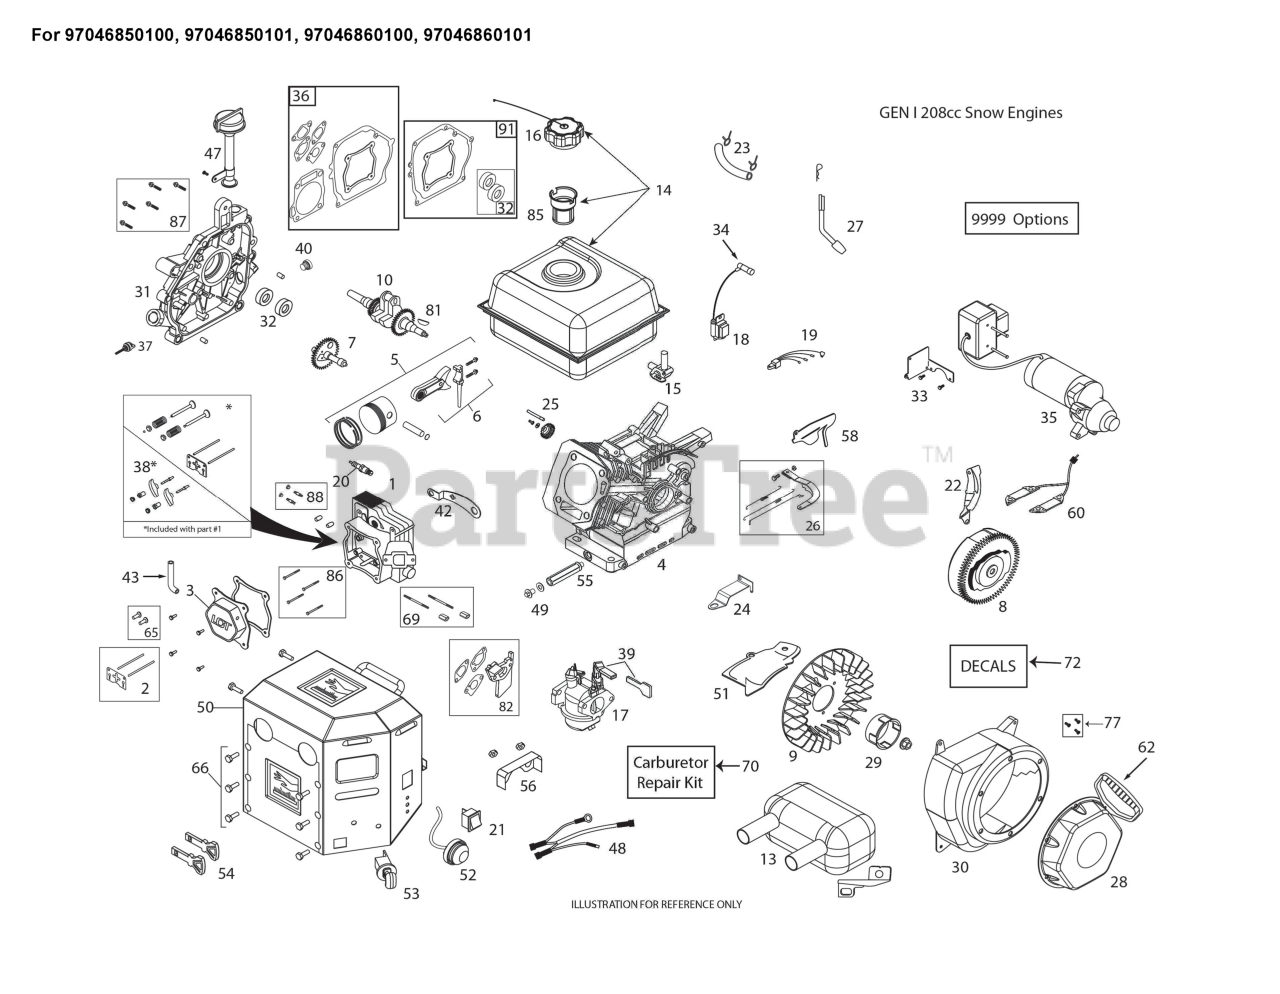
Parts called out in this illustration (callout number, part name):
1	CYLINDR.HEAD.SRV.KIT W/GASKET
2	KIT.PUSH.ROD.SRV(SK208-1001)
3	VALVE COVER LCT 179/208
5	KIT.PISTON.SRV(SK208-1400)
7	KIT.CAMSHAFT.208CC.LCT
8	FLYWHEEL ELECTRIC START W/6 MA
9	FLYWHEEL FAN 420586
10	CRNKSHFT-KYD#14.208CCSKSNO8001
13	MUFFLERS
13	Husqvarna TBD
13	MUFFLER KIT LCT SKSN2205.1
14	FUEL.TK.ASSY.GENII.SKSN0311.1
15	FUEL.PETCOCK.SNOW(SKSN4900)
16	FUEL CAP OVERSIZED CLICK STYLE
17	CARBURETORS
17	CARBURETTOR L10-1D.W/SP
18	208CC IGN COIL (STD)
20	SPARK.PLUG(2083810)
22	SHIELD.FLYWHEEL.ELEC.STRT.208C
23	KIT.FUEL.HOSE.208CC.SING/STAGE
24	SPEED.CTRL.BRKT.(SKSN0150)
25	GOVENOR.GEARS ASM(SK2082900)
26	CARBURETTOR GOVERNOR LINK.ASM.
27	KIT.GOVERNOR.CRANK(SK208-3100)
28	RECOIL.STRT.ROUND(BLK) SNOW
29	STRTER.CUP(NON-SLOT)SKSN0601.2
30	HOUSINGS
31	COVER CRANKCASE.LCT.SK2083605
32	SEAL KIT (2 PCS)
34	SPARK.PLUG.BOOT.SNW,SKSN4691.1
35	STARTER 230C EL START.LCT SKSN
35	ELEC.START.GEN2.SKSN0451.1
36	GASKET.KIT.208CC(SK2084300.1)
37	DIPSTICK SMALL
38	ROCKER ARM KIT
39	CHOKE.KNOW.SNOW(SKSN4500)
40	NON REMOVABLE PLUG
43	TUBE.BREATHER.LCT.208
47	TUBE ASSY HIGH OIL-FILL
48	HARNESS WIRE. W/O OFF/ON SWITC
49	KIT.OIL.DRAIN.PLUG(SK2089911
50	BOX HEATER.W/O OFF/ON SWITCH.L
51	SHIELD.CYLINGER.LCT.SKSN0608.2
52	STARTER SCREW.STARTER SWITCH B
52	PRIMER.BULB.WITH HOSE (SNOW)
53	SWITH.KEY.ASSEM.SNOW.SINGLE.ST
54	KEY SET(2 KEYS) SKSN0407.1
55	EXTENDED OIL DRAIN TUBE
56	SHIELD GOVENOR & CARB - COMPOS
57	SHIELD.MUFFLER.CE.COMPLIANT
58	SHIELD GOVENOR & CARB - COMPOS
59	FUEL.TNK.SKRT.GENII.SKSN0103.1
60	208CC 60W ALTERNATOR
61	FUEL KNOB-SNOW
65	TAPPET.KIT.LCT.208CC
69	CARB.STUDS & COUPLING KIT.SNOW
70	CARBURETOR.REPAIR KIT.LCT.
72	HOP SNOW DECAL KIT
74	MUFFLER GUARD.EUR./LCT.SKSN220
77	BOLT.KIT.RECOIL.LCT.ALL.ENGINE
81	KEYS.FLYWHEEL.208/414CC.5PACK
82	SPACER.CARBURETOR.208CC.LCT
85	STRAINER.FUEL.TANK.LCT.208CC
86	BOLT KIT.CYLINDER HEAD.LCT(4)1
87	KIT.BOLT.CRANKCASE.COVER.6PC
88	STUD.MUFFLER.KIT.LCT
91	COVER CRANKCASE GASKET
97	GUARD.MUFFLER.MANIFOLD.LCT
9999	BOLTS
9999	KIT.BOLT.LCT.SK9990.1
9999	STARTER SCREW.STARTER SWITCH B
9999	HIGH.ALTITUDE.JET 6,000FT
